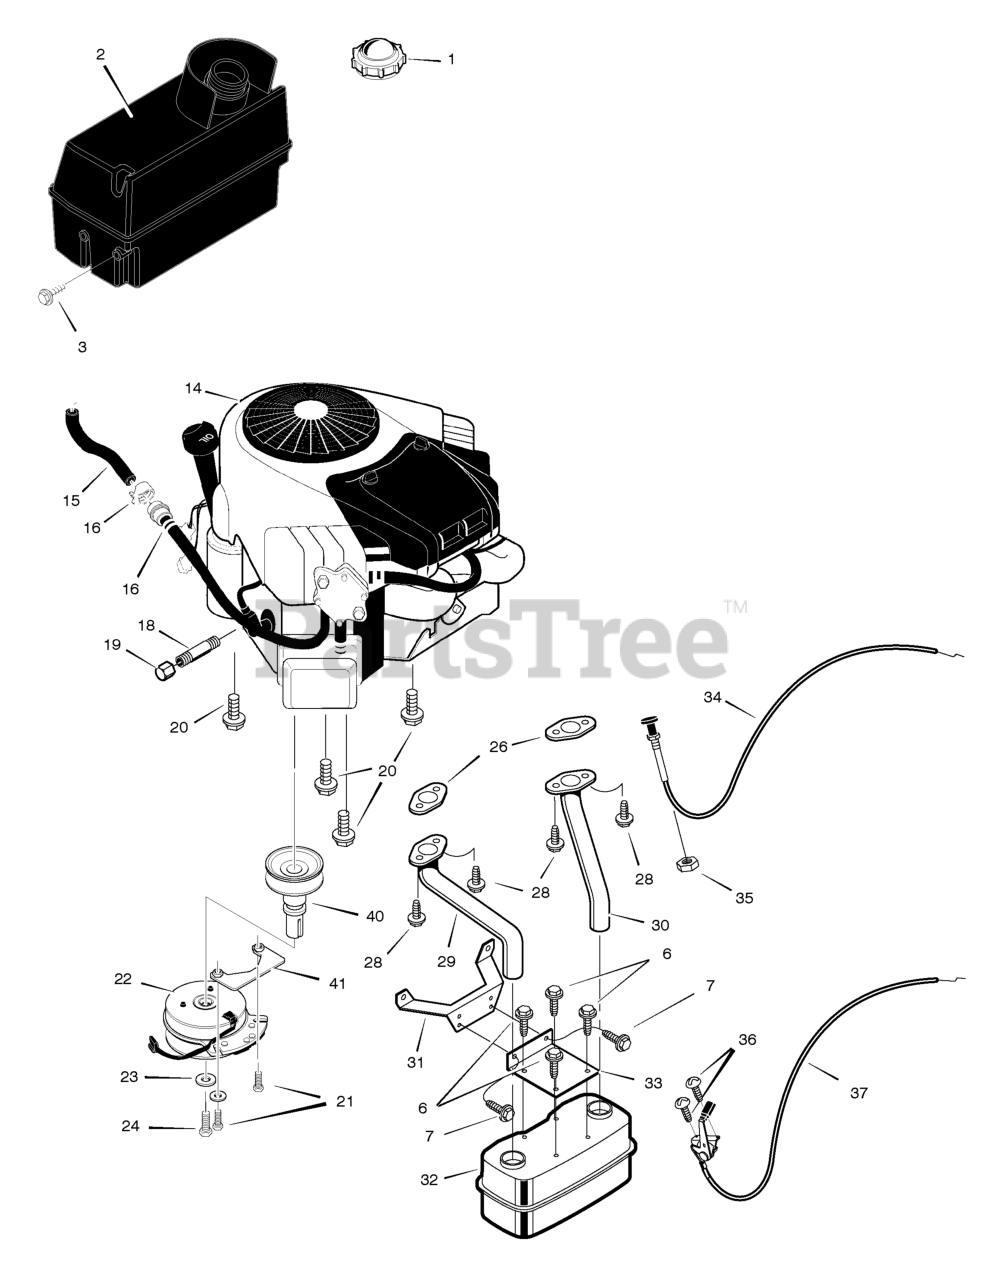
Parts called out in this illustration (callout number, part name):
1	Cap, Fuel
2	Tank, Fuel
14	Engine, Briggs & Stratton *
15	Fuel Line (Must cut to length)
16	Clamp
18	Pipe, Oil Drain
19	Cap, Oil Drain
20	Bolt
22	Clutch, Electric
23	Washer
29	Tube, Right Exhaust
30	Tube, Left Exhaust
31	Bracket, Muffler Mount
32	Muffler
33	Bracket, Muffler
35	Nut
37	Control, Throttle
40	Adapter, Pulley
41	Plate, Brake
